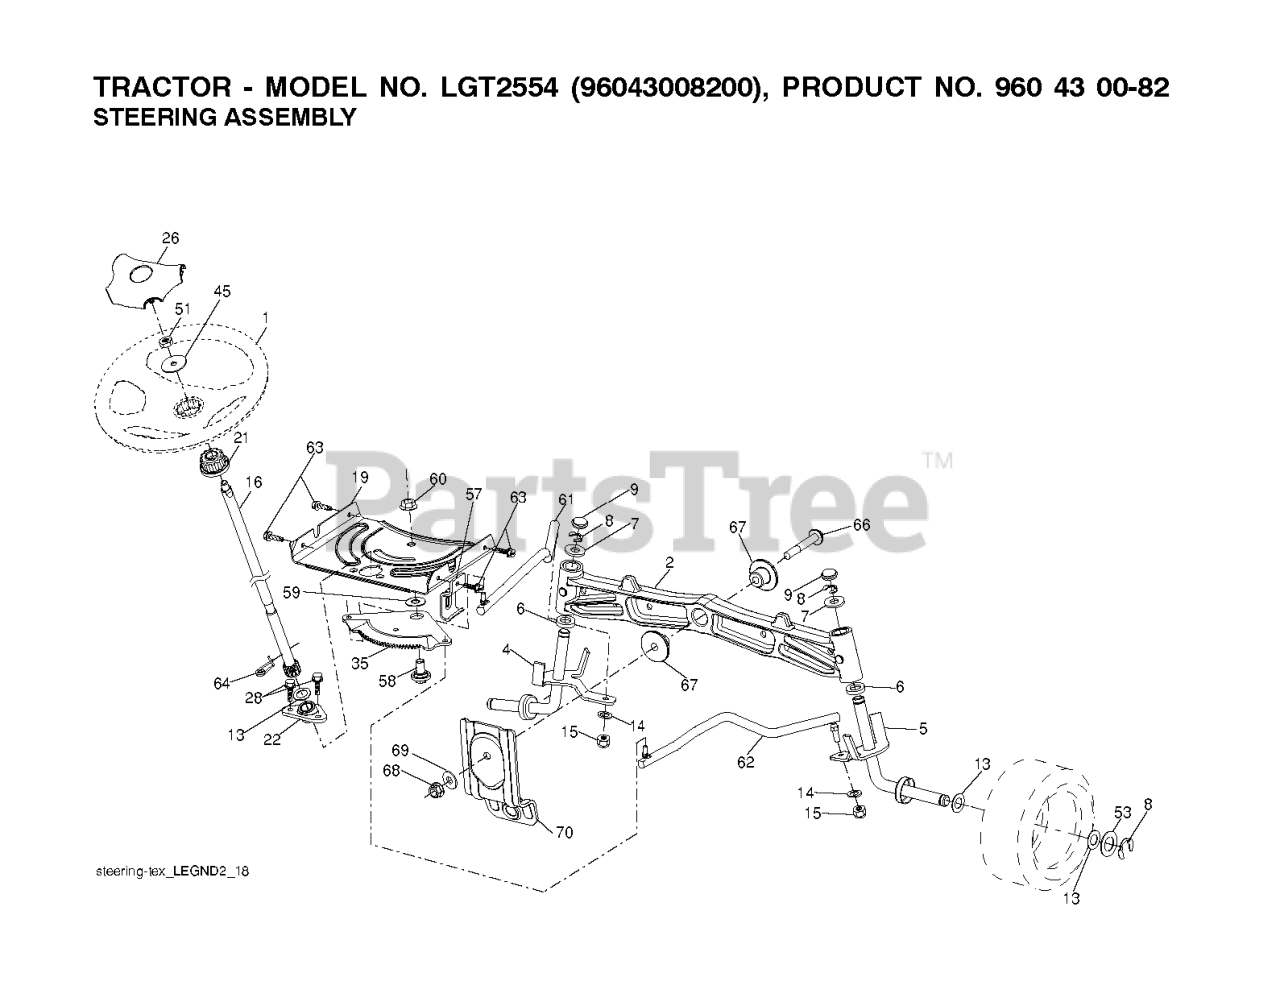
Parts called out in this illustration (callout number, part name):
1	WHEEL STEERING
2	AXLE.CAST.IRON
4	SPINDLE.WELDED.LH.16"TEX
5	SPINDLE.WELDED.RH.16"TEX
6	THRUST WASHER
9	CAP.SPINDLE.BLACK
14	WASHER, LOCK 3/8
15	NUT CROWNLOCK 3/8-24
16	SHAFT, STEERING
19	PLATE.STEER.DDL.NLT/NG
21	ADAPTER, WHEEL STNG..
22	BUSHING.ASM.STEERING.A
26	RP INSERT.CAP.WHL.STRG.HUSQ.
28	SCREW, 3/8-16X3/4
35	GEAR.SECTOR.PLATE.DDL.
45	WASHER 9/16"ID, 2 3/8"OD
51	NUT.HEX.1/2-20
53	WASHER.HARDENED
57	BRKT.UPSTOP.GT/LT.TEX
58	BOLT.SHOULDER.SECTOR.P
59	WASHER.THURST.SECTOR.S
60	NUT FLANGE LOCK 5/8-11
61	DRAGLINK.LH.BALLSTUD.D
62	DRAGLINK.RH.BALLSTUD.D
63	SCREW
64	RETAINER.CLIP.SPRING.S
66	BOLT HEX FGHD 7/16-14 X 3 SERR
67	BUSHING.PM.FRONT AXLE
68	NUT.LOCK.FLANGE.7/16
69	WASHER.1.5X.505X.118
70	BRKT.DECK.SUSPENSION.F
